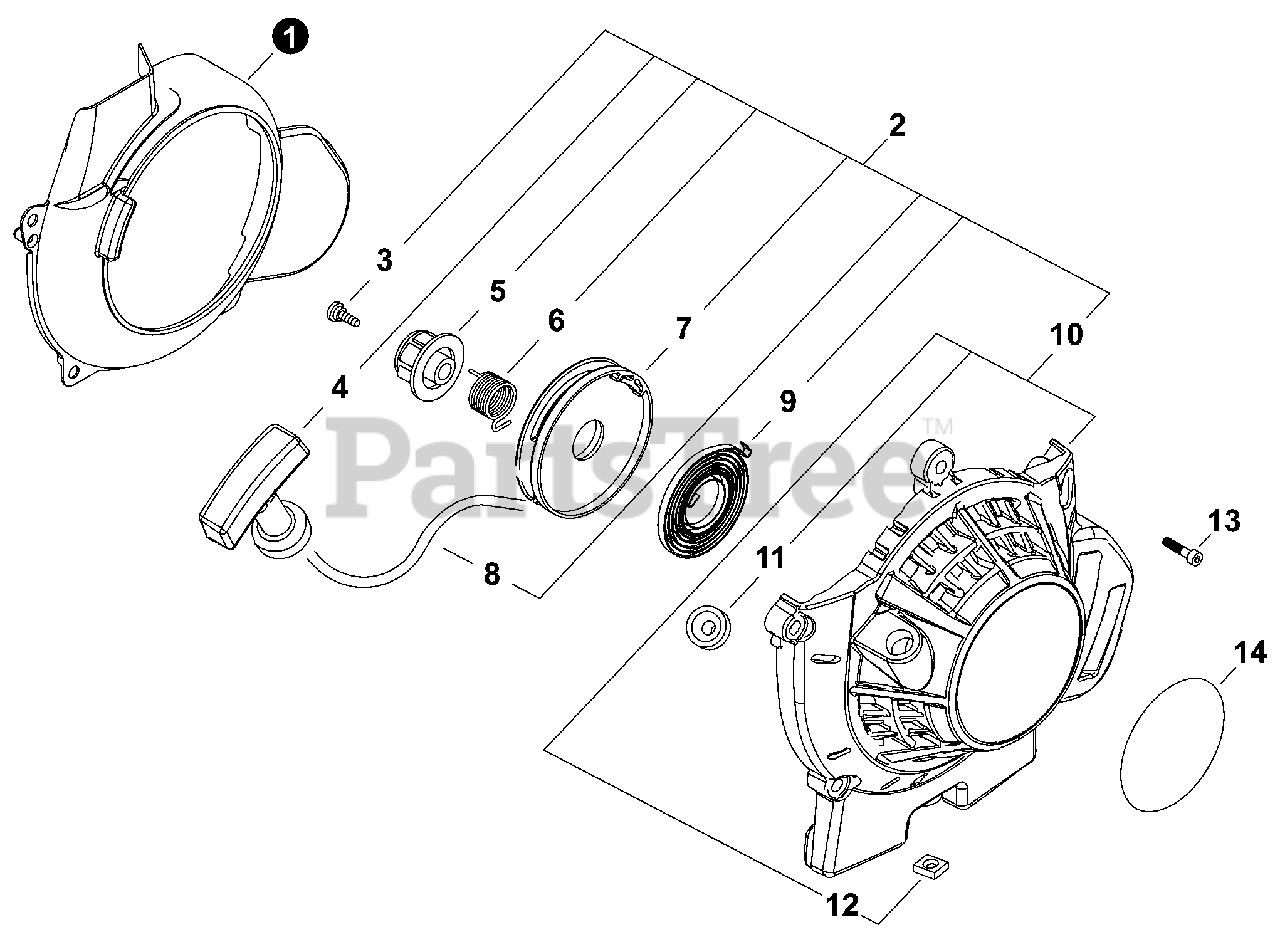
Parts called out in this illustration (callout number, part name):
1	COVER, FAN
2	STARTER ASSY, RECOIL
4	GRIP, STARTER
6	SPRING, TORSION
7	REEL, ROPE
8	ROPE, STARTER
9	SPRING, RECOIL
10	CASE, STARTER
11	GUIDE, ROPE
12	NUT M5
13	BOLT, TORX 5x20
14	LABEL - RECOIL STARTER
